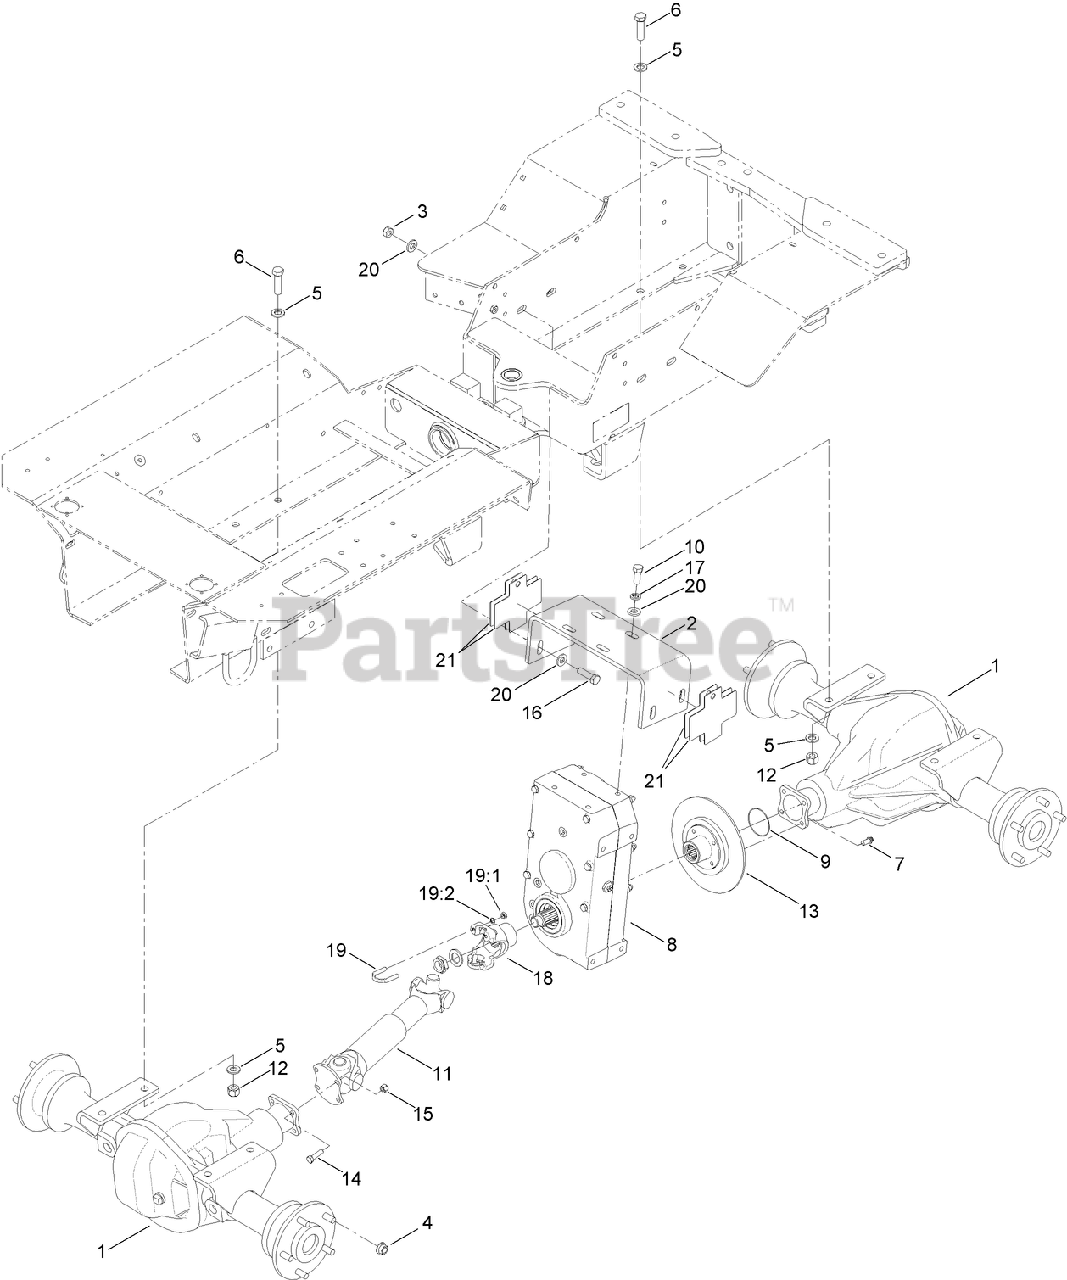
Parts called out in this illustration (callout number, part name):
1	AXLE-DRIVE
2	BRACKET-MOUNTING
3	LOCKNUT
5	WASHER-FLAT
7	SCREW-12 PT FLANGE
8	TRANSMISSION ASM
9	O-RING, SAE
10	SCREW-HH
11	DRIVE SHAFT ASM
13	FLANGE-COMPANION
14	SCREW-HH
15	NUT-HEX
16	SCREW-HH
17	WASHER-LOCK
18	YOKE-TRANSMISSION
19	BOLT-U (2 PER PACK)
19:1	NUT-HEX
19:2	WASHER-LOCK
21	Shim-Bracket
